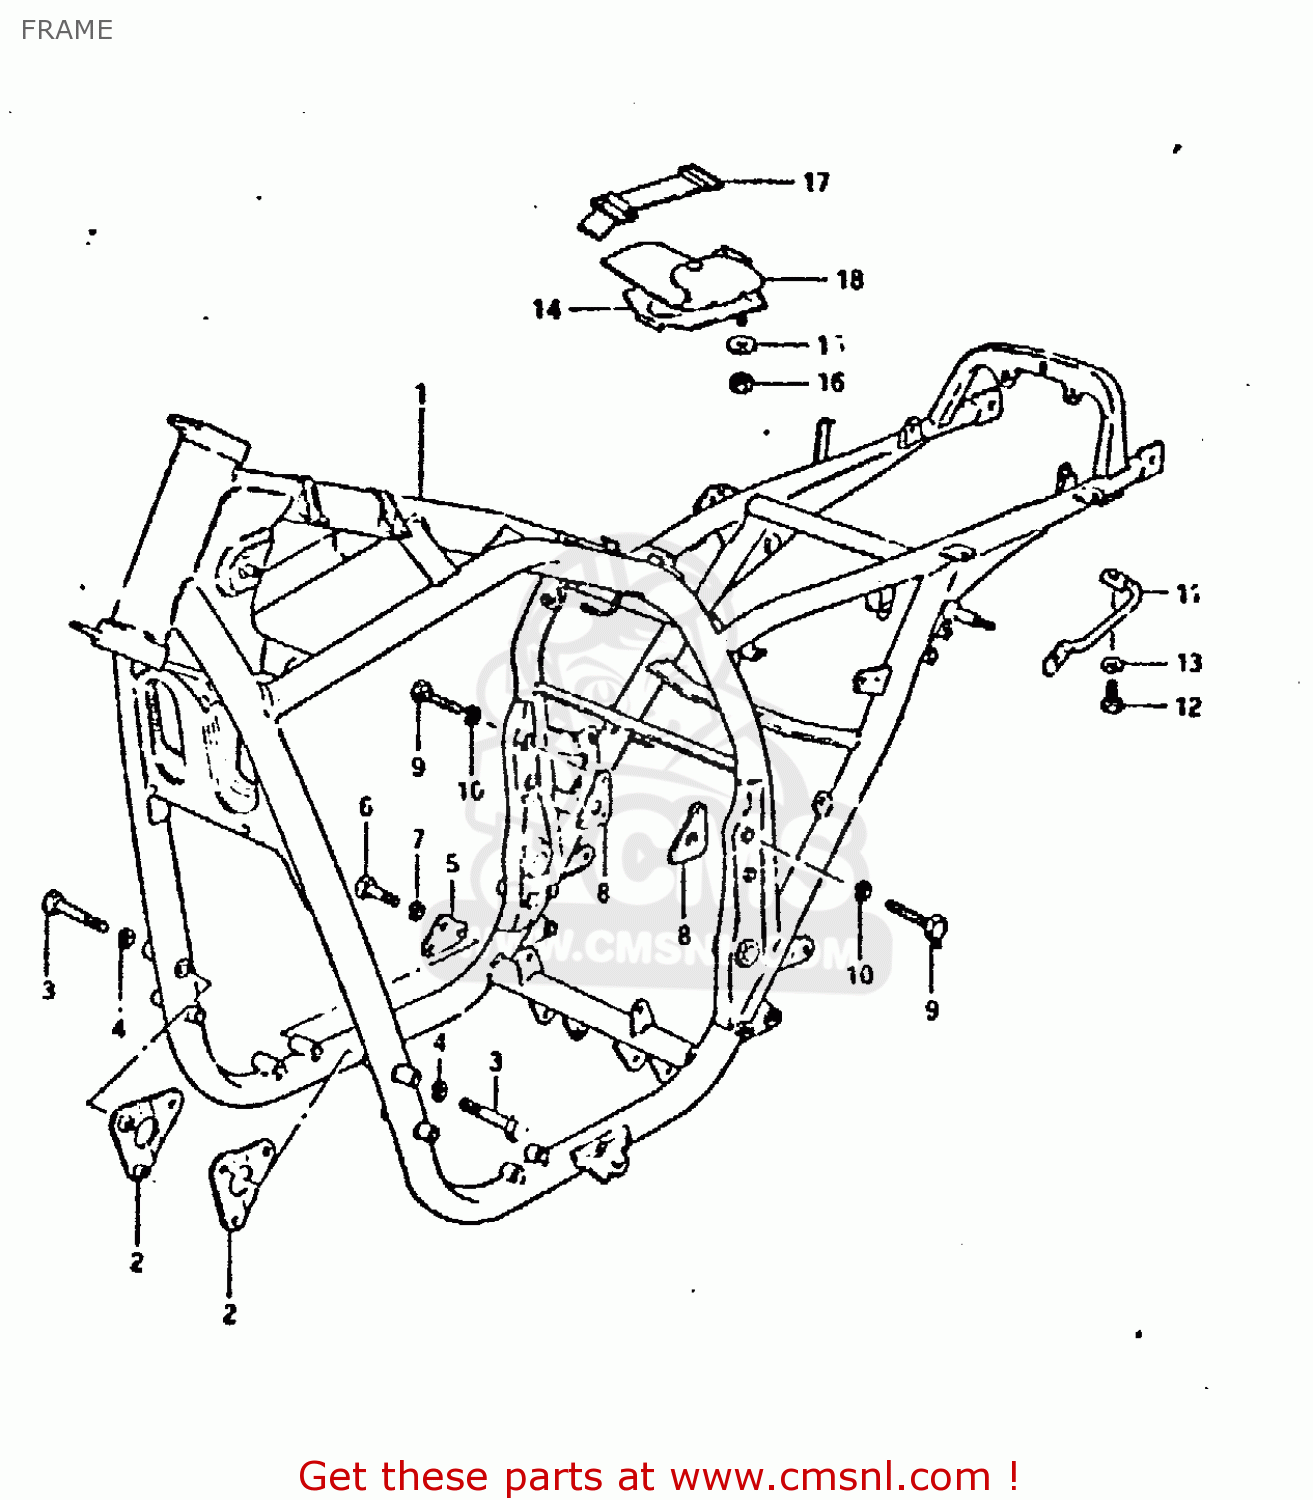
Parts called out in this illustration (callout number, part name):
1	FRAME
2	PLATE,ENG MTG NO.1
3	BOLT
4	LOCK WASHER
5	PLATE,ENGINE MOUNTING
6	BOLT
7	LOCK WASHER
8	PLATE,ENGINE MOUNTING
9	BOLT
10	LOCK WASHER
11	GRIP,FRAME
12	BOLT
13	WASHER
14	HOLDER,TOOL
15	WASHER
16	NUT
17	BAND
18	TOOL SET
